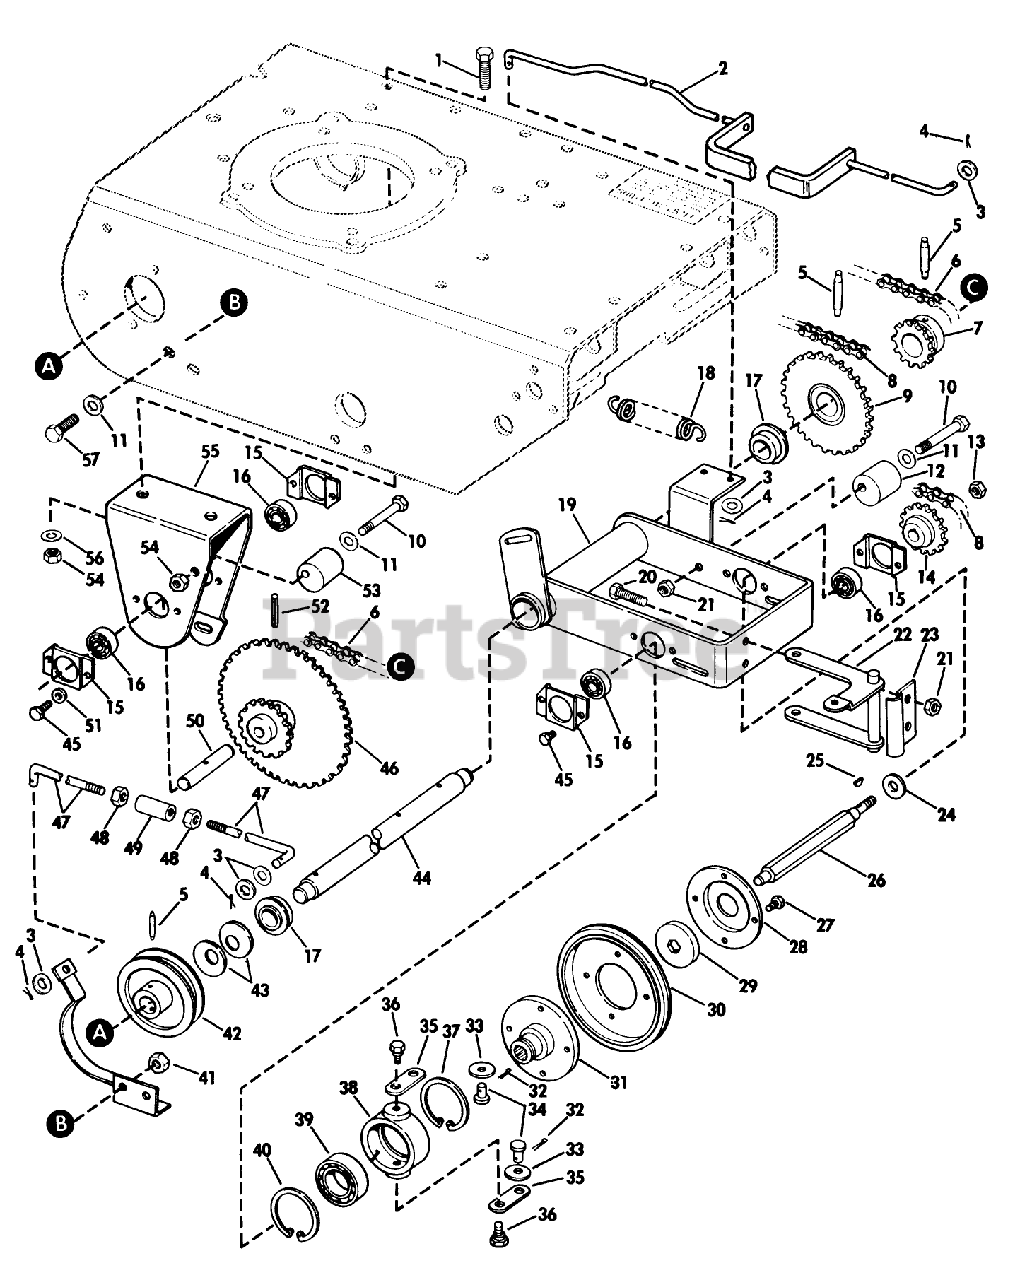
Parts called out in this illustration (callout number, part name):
13	LOCKNUT
30	DRIVE WHEEL
48	STOP NUT
54	LOCKNUT
